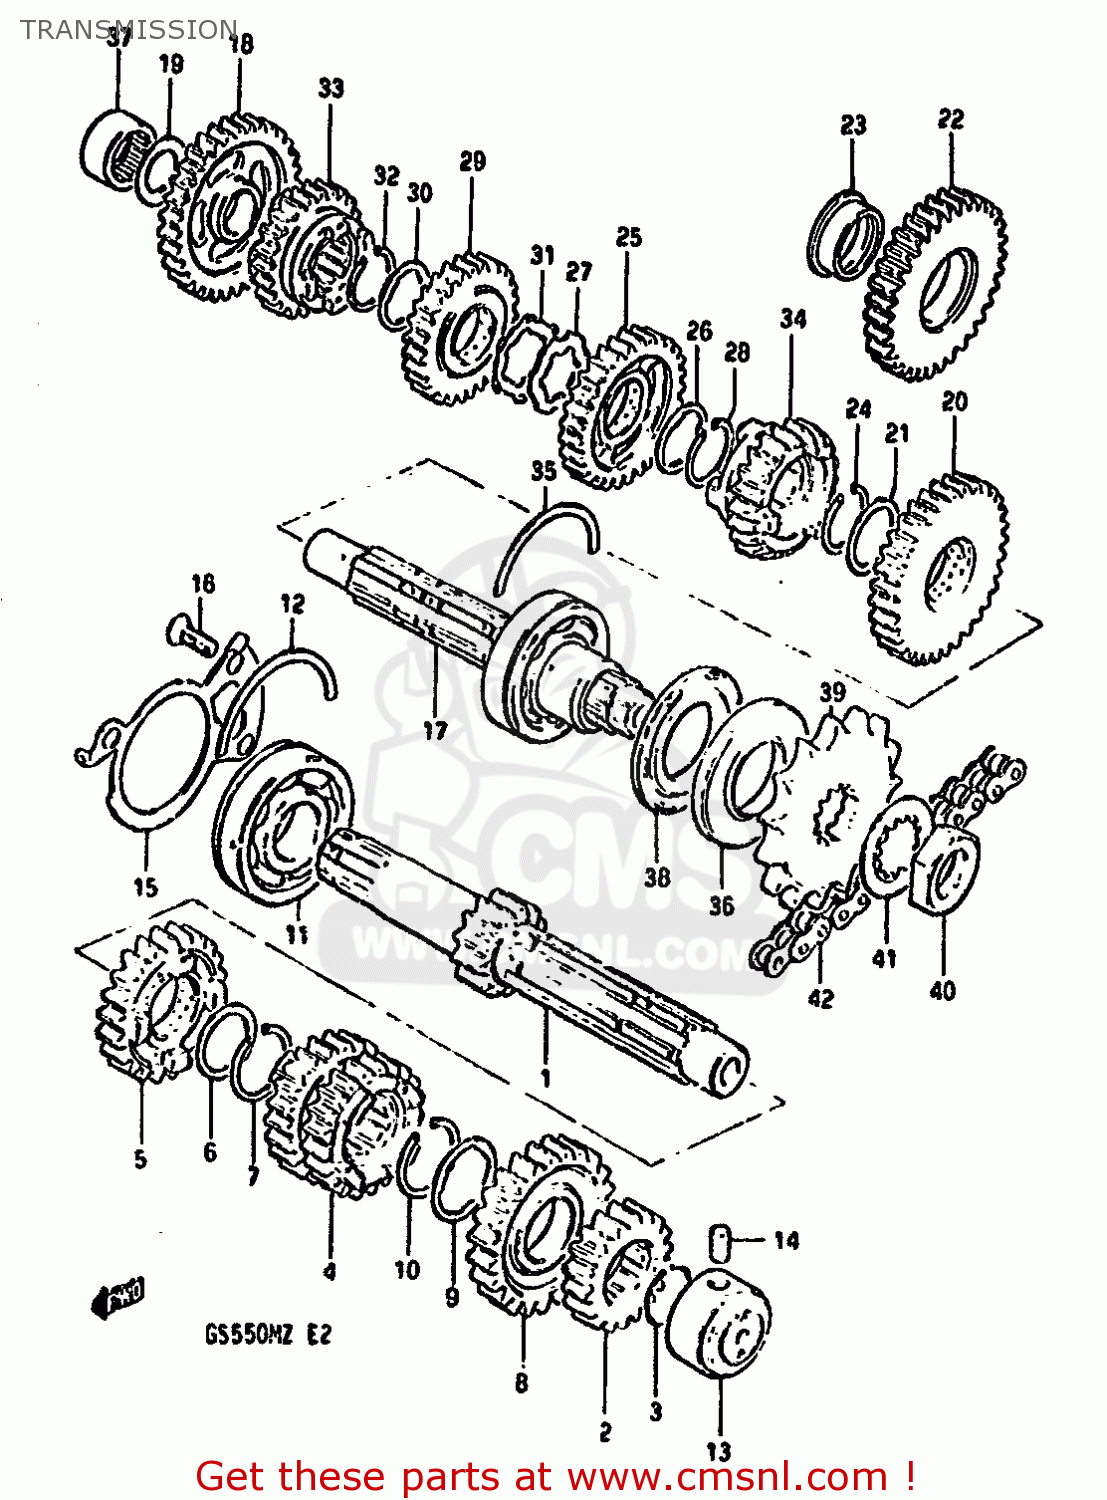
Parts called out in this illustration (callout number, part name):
1	SHAFT,COUNTER
2	GEAR,SECOND DRIVE
3	RING,SNAP
4	GEAR,THIRD DRIVE
5	GEAR,FIFTH DRIVE
6	WASHER
7	CIRCLIP
8	GEAR,SIXTH DRIVE
9	WASHER,LOCK
10	CIRCLIP
11	BEARING(25X62X17)
12	C-RING
13	BEARING
14	PIN
15	PLATE,COUNTERSHAFT BEARING
16	SCREW
17	SHAFT,DRIVE
18	GEAR,FIRST DRIVEN
19	WASHER
20	GEAR,SECOND DRIVEN
21	WASHER
22	GEAR,SECOND DRIVEN
23	BUSHING
24	CIRCLIP
25	GEAR,THIRD DRIVEN
26	WASHER,LOCK
27	WASHER,LOCK
28	CIRCLIP
29	GEAR,FOURTH DRIVEN
30	WASHER,LOCK
31	WASHER
32	CIRCLIP
33	GEAR,FIFTH DRIVEN
34	GEAR,SIXTH DRIVEN
35	C-RING
36	SEAL,OIL(32X62X7)
37	ROLLER BEARING (20X34X1
38	SEAL,OIL(32X62X5.5)
39	SPROCKET,ENGINE
40	NUT
41	WASHER
42	CHAIN ASSEMBLY,DRIVE
